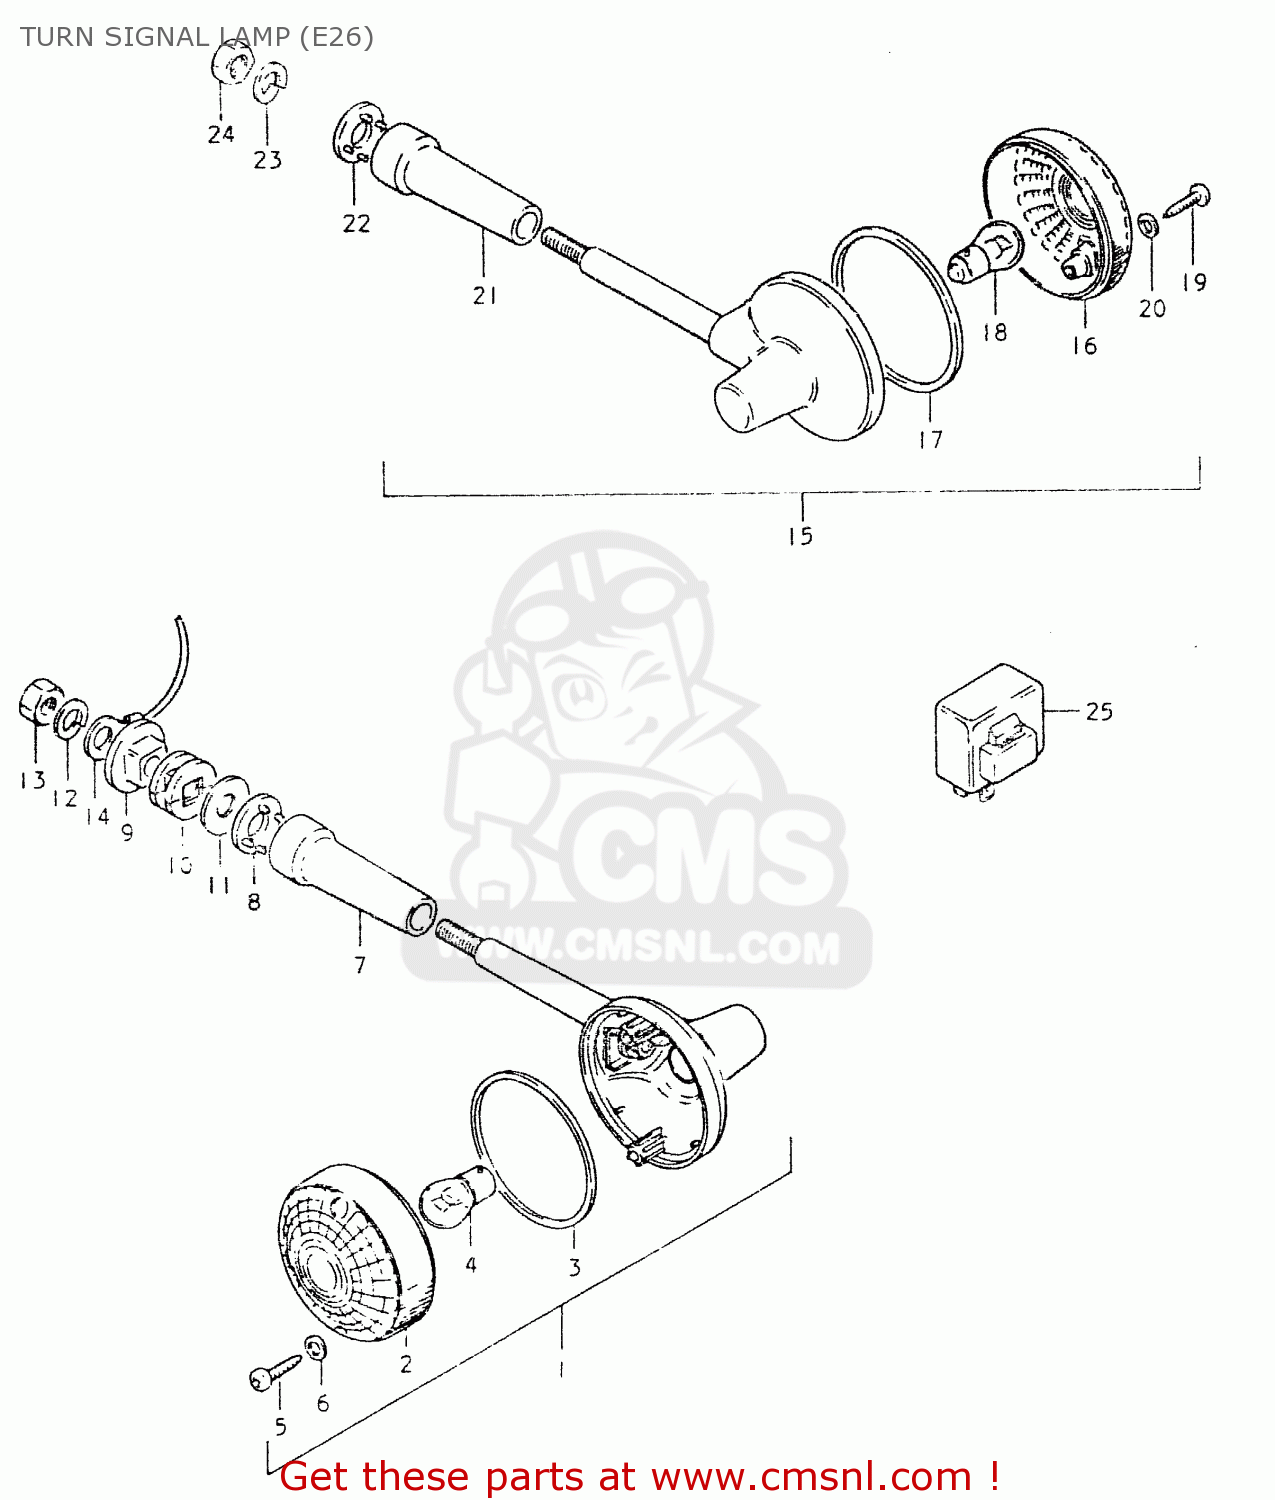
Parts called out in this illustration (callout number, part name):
1	LAMP ASSY FRON
2	LENS
3	GASKET (NAS)
4	BULB 12V 21W
5	SCREW
6	GASKET (NAS)
7	COVER,STAY
8	SPACER
9	SPACER,TURN SIGNAL LAMP
10	CUSHION
11	WASHER (10.5X30X2.3)
12	LOCK WASHER
13	NUT
14	WIRE
15	LAMP, REAR TURN SIGNAL
16	LENS
17	GASKET (NAS)
18	BULB 12V 21W
19	SCREW
20	GASKET (NAS)
21	COVER,STAY
22	SPACER
23	LOCK WASHER
24	NUT
25	RELAY,TURN SIGNAL
